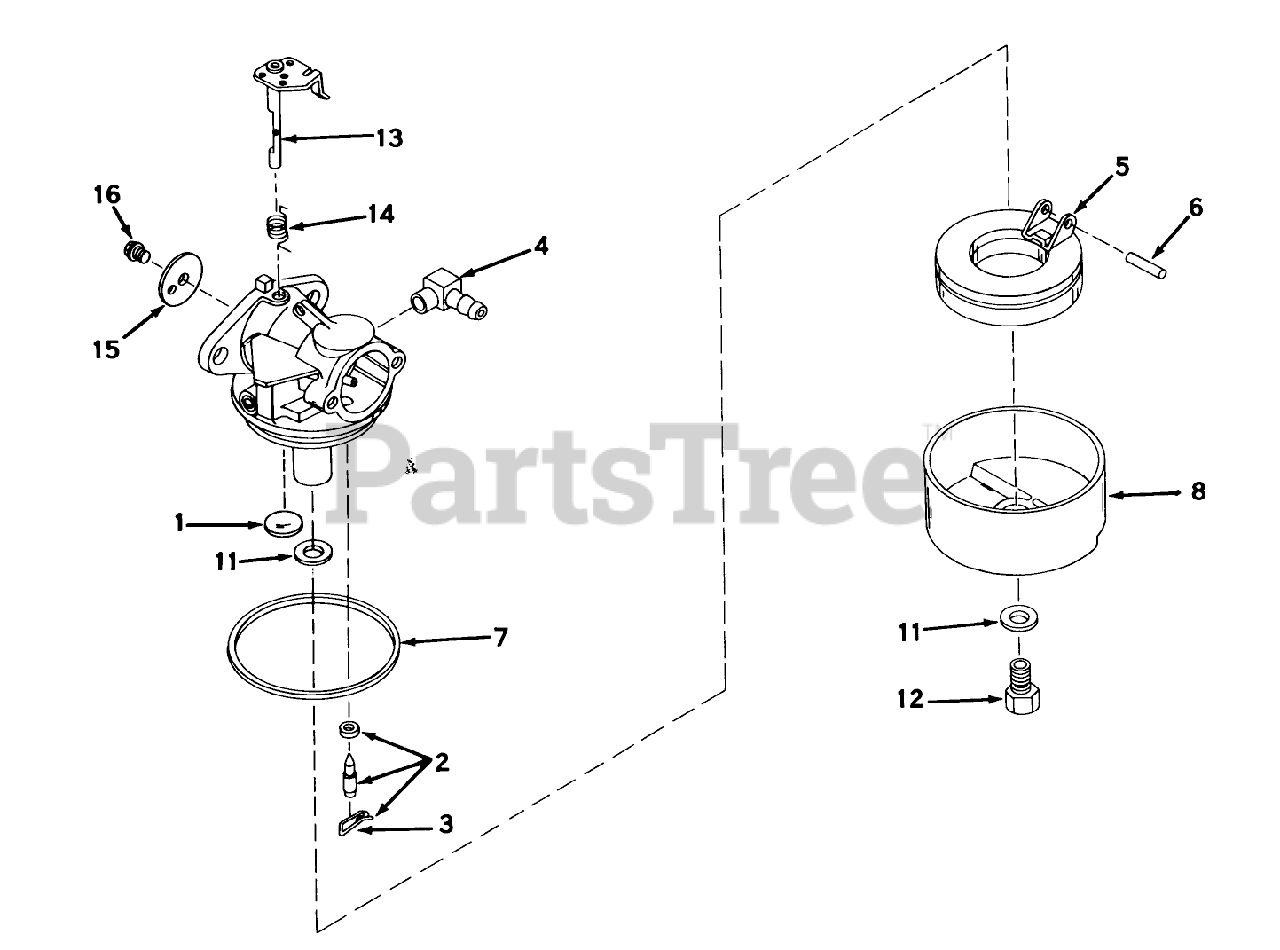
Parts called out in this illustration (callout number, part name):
1	Plug-Welch, Atmospheric Vent
2	Inlet Needle, Seat Clip Assy. (Incl. No. 3)
3	Clip-Spring
4	Fitting-Fuel
5	Float,Carburetor
6	Shaft-Float
7	O Ring-Bowl, Float
8	Bowl Float
11	Gasket-Bowl
12	Nut, Float Bowl
13	Throttle Shaft and Lever ASM
14	Spring, Return
15	Throttle-Shutter
16	Screw-Shutter
